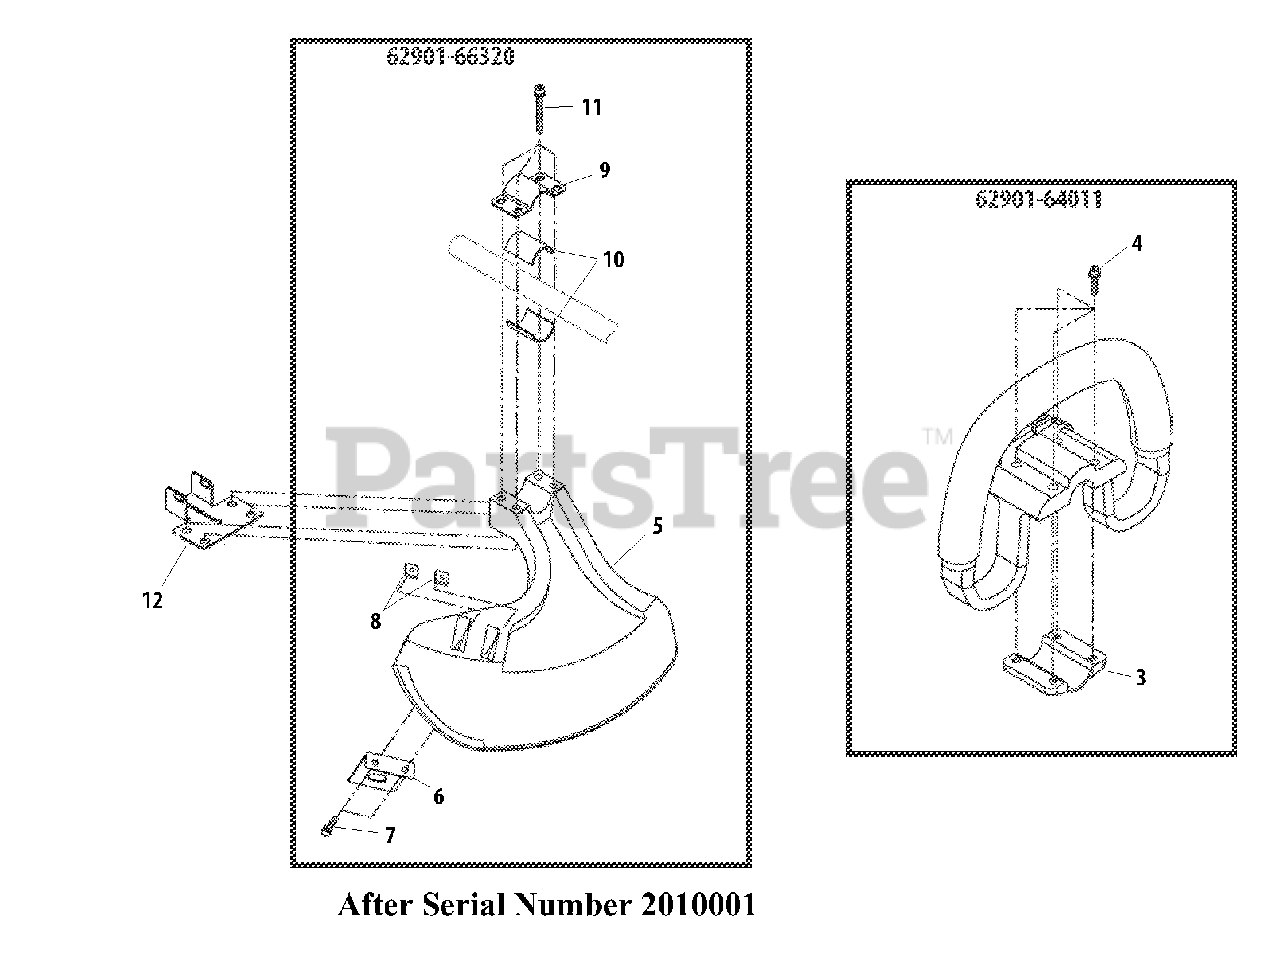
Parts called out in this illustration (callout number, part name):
3	CLAMP - LOWER
4	SCREW - 5X25
5	SHIELD
6	KNIFE, TRIMMER LINE
7	SCREW - 5X16
8	NUT - 5
9	CLAMP - UPPER
10	SPACER
11	SCREW - 5X45
12	CLAMP - LOWER
62901-64011	HANDLE ASSY
62901-66320	GUARD ASSY
